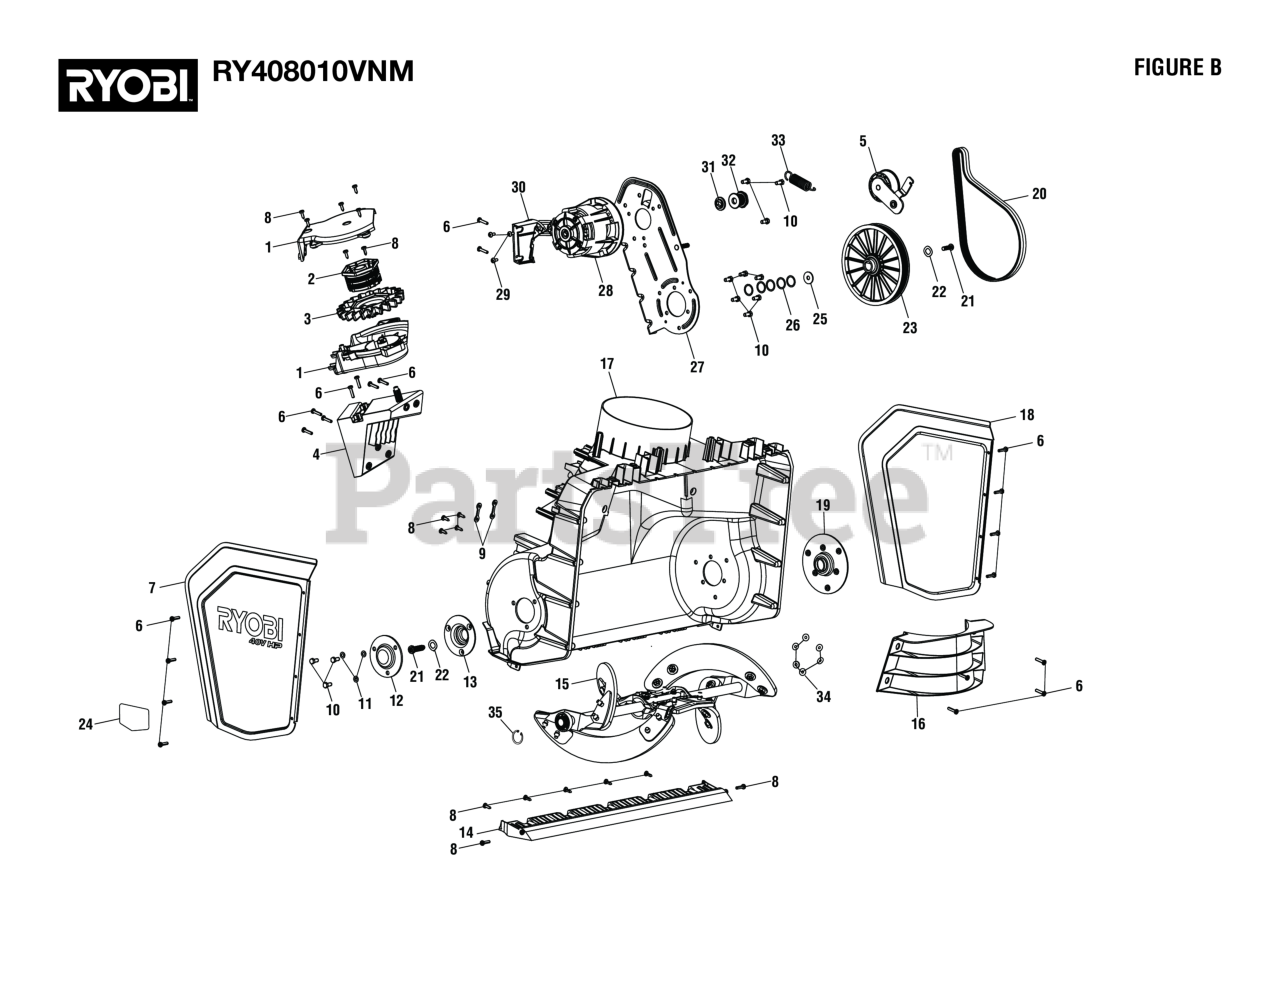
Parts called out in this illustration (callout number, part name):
1	Chute Cover Assembly
2	Pinion Drum
3	Pinion Gear
4	Mounting Plate
5	Sheet Metal Bracket
6	Screw (M4 x 18 mm, T20 Torx Pan Hd. S.T.)
7	Right Side Cover
8	Screw (M4.2 x 12 mm, T20 Torx Pan Hd.)
9	Hold-Down Tab
10	Screw (M5 x 12 mm, Hex Hd.)
11	Washer (OD9.8 x ID5.3 x 0.8t)
12	Auger Bearing Cover Plate
13	Bearing Retainer
14	Scraper Blade
15	Snow Thrower-Auger Assembly
16	Lower Chute Neck
17	Lower Body
18	Left Side Cover
19	Bearing Retainer Plate
21	Screw (M6 x 20 mm, T27 Torx Button Hd.)
22	Wave Washer
23	Auger Pulley
24	Danger Label (No Hands/Feet)
25	Flat Washer, ID6.6XOD20XT1.6, 65Mn,
26	Flat Washer (ID15.1 x OD19 x 0.5t)
27	Motor Mounting Plate
29	Screw, M4X0.7, SCM435, Black Zinc Plated
30	Motor Mounting
32	Motor Pulley
33	Belt Tensioner Spring
34	Flat Washer
